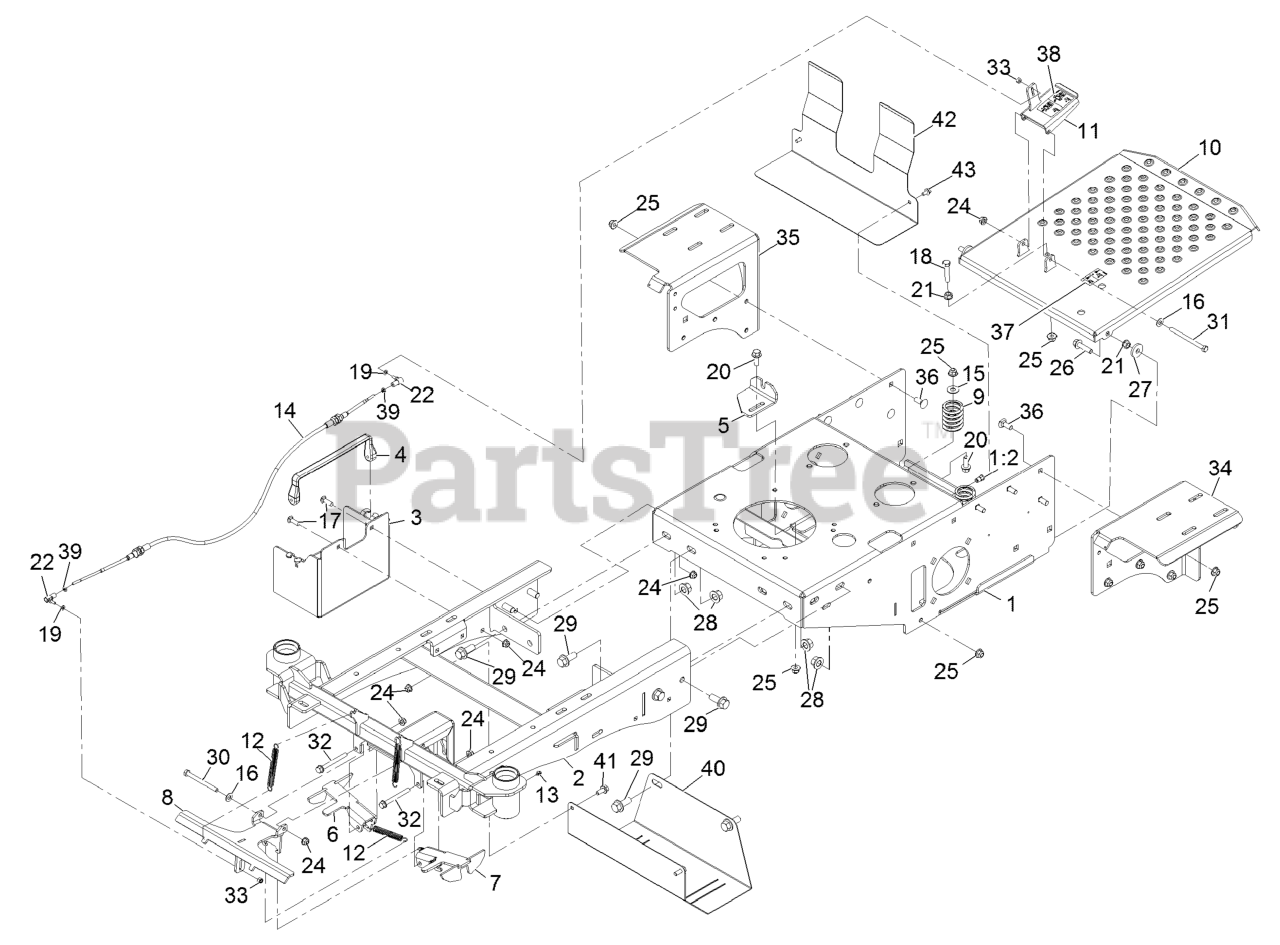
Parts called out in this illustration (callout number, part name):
1	FRAME-REAR
1:2	NUT-CLINCH,HEX
2	WLD, FRONT FRAME, JR36 24
3	BOX-BATTERY
4	BUNGEE (TARP STRAP)
5	Bracket, Lower Cable
6	Wing-Capture, Rt
7	Wing-Capture, Lt
8	WLD, CAPTURE, T-BAR, JR36
9	SPRING-COMPRESSION
10	WLD, FOOT PLATE, JR36
11	Wld, Foot Pedal, Lcs
12	SPRING-EXTENSION
13	FITTING-GREASE, ZERK
14	CABLE-CASTER, LOCKING
15	WASHER-FLAT
17	Bolt,Carriage,5/16-18X1,ST/ST 18-8
18	Screw-HH
19	WASHER-FLAT
20	SCREW-HHF
21	Nut-Hex Flange
22	BALL JOINT-SS
24	Nut-Hex Flange
25	Nut-Hex Flange
26	SCREW-HHF
28	NUT-HEX FLANGE
29	SCREW-HHF
30	SCREW-HH
31	Screw-HH
32	SCREW-HHF
33	Nut,NYL Lock,#10-32,ST/ST 18-8
34	WLD, MOUNT, FERT BOX, L, JR36
35	WLD, MOUNT, FERT BOX, R,
36	SCREW-CARR
37	Decal-Spray Foot Button
38	Decal-Lock, Caster
39	Nut,Hex Jam Mch Scr,10-32,Sst
40	GUARD, MUFFLER, JR36
41	SCREW-HHF
42	Shield, Heat, HYD Pump, Jr36
43	SCREW-HHF
